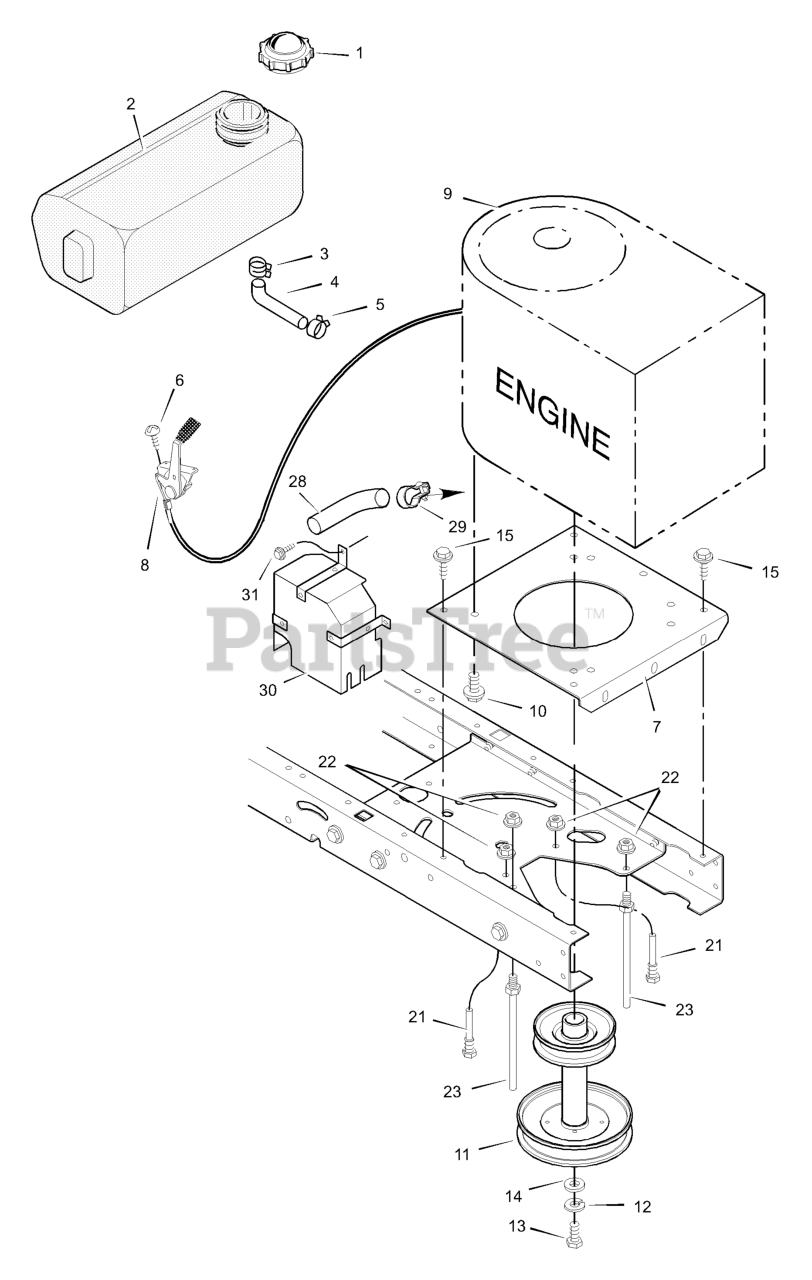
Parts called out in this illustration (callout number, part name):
1	Fuel Cap
2	Fuel Tank
3	Hose Clamp
4	Fuel Line
5	Hose Clamp
7	Plate, Engine
8	Throttle Control
9	Engine
10	Bolt, Engine Mount
11	Stack Pulley Assembly
12	Lockwasher
13	Bolt, Hex
21	Guide, Belt
22	Nut, Flange
23	Guide, Belt
28	Pipe, Exhaust
30	Shield, Heat
